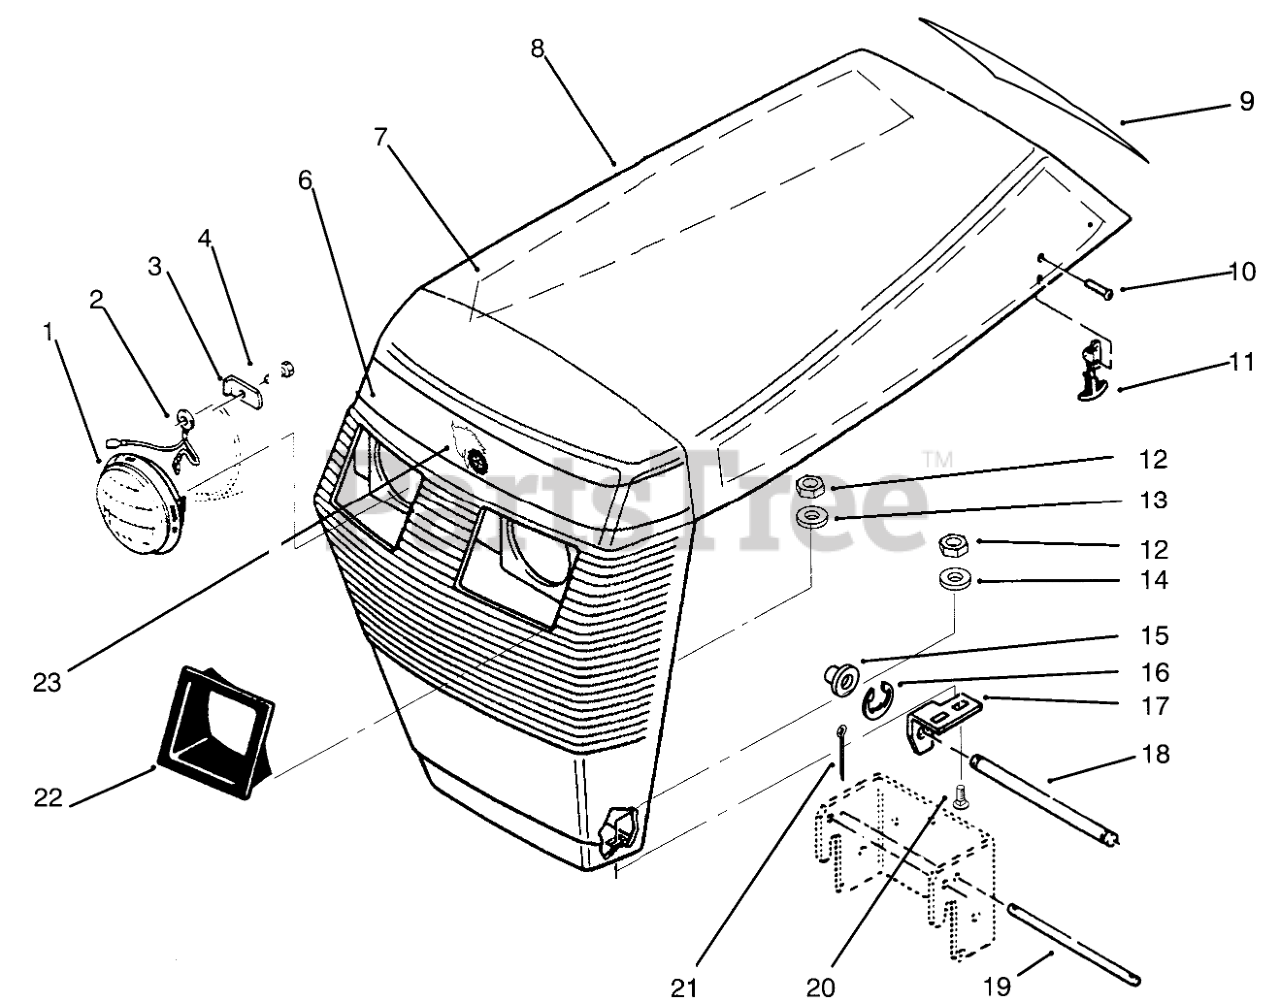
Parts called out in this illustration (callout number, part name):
1	HEADLAMP
2	LIGHT GROUND WIRE
3	LOCK-HEADLIGHT
4	Bolt
6	DECAL-FRONT HOOD, TOP
7	DECAL - RH HOOD TOP
8	Hood(Incl. Ref. # 9)
9	DECAL - DANGER
10	RIVET-POP
11	HANDLE ASM
12	NUT-LOCK, NI
13	WASHER-LOCK, INTERNAL
14	WASHER-FLAT
15	BUSHING-NYLINER
16	RING-RETAINING
17	BRACKET-GRILL, LH
18	ROD-GRILL PIVOT
19	ROD-HOOD STOP
20	SCREW-CARR
21	PIN-COTTER
22	BEZEL-HEADLIGHT, LH
23	PLATE - LOGO WHL HORSE
